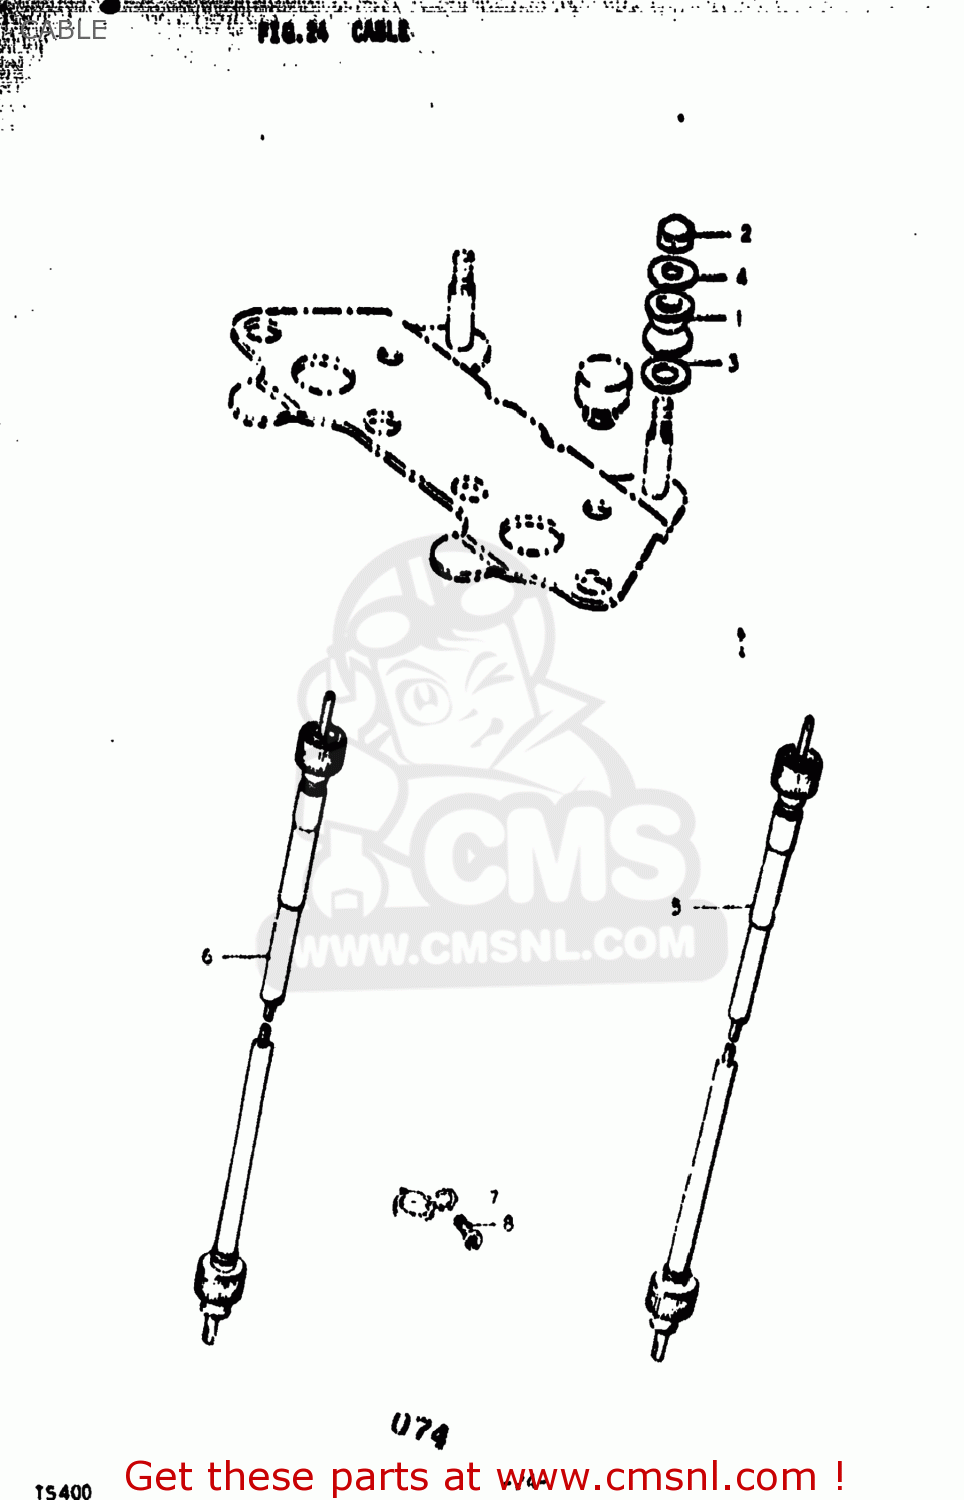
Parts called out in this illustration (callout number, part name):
1	CUSHION
2	NUT
3	WASHER
4	WASHER
5	CABLE ASSEMBLY,SPEEDOMETER
6	CABLE ASSEMBLY,TACHOMETER
7	SCREW
8	SCREW
